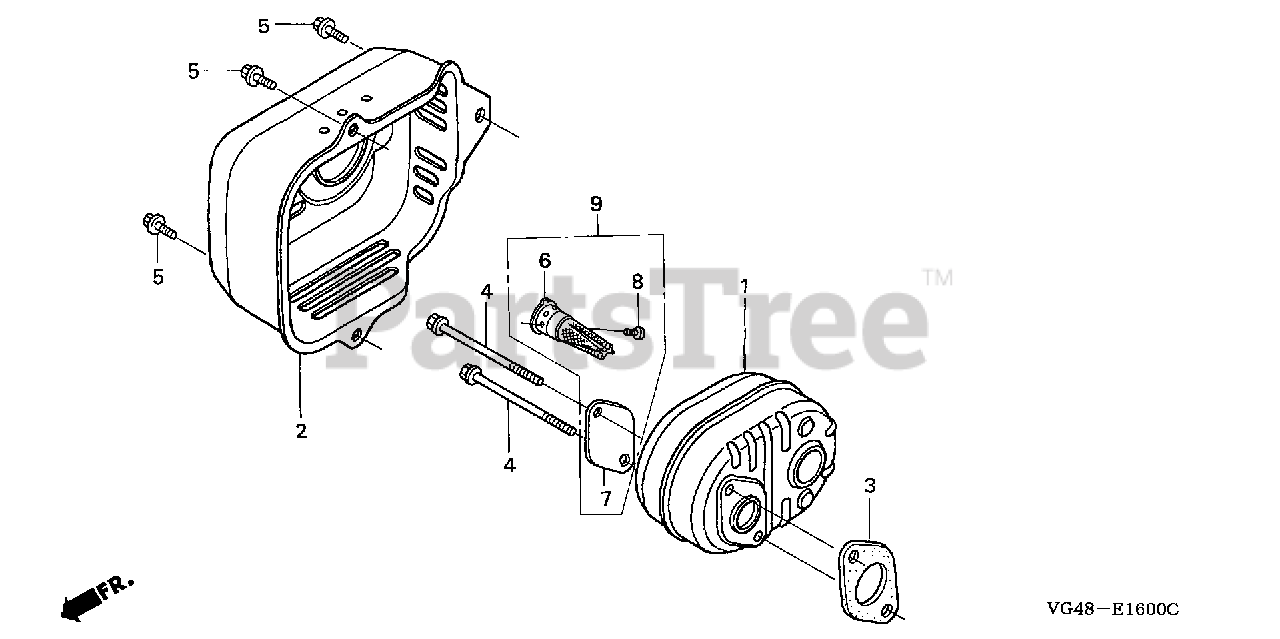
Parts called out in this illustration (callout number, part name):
1	MUFFLER
2	PROTECTOR, MUFFLER
3	GASKET, MUFFLER
4	BOLT, FLANGE (6X79) (CT200)
5	BOLT, FLANGE (6X12) (CT200)
6	ARRESTER, SPARK (OPTIONAL)
7	PLATE, ARRESTER NUMBER (TO INSTALL OPTIONAL SPARK ARRESTER)
8	SCREW, TAPPING (4X6) (TO INSTALL OPTIONAL SPARK ARRESTER)
9	ARRESTER KIT, SPARK
